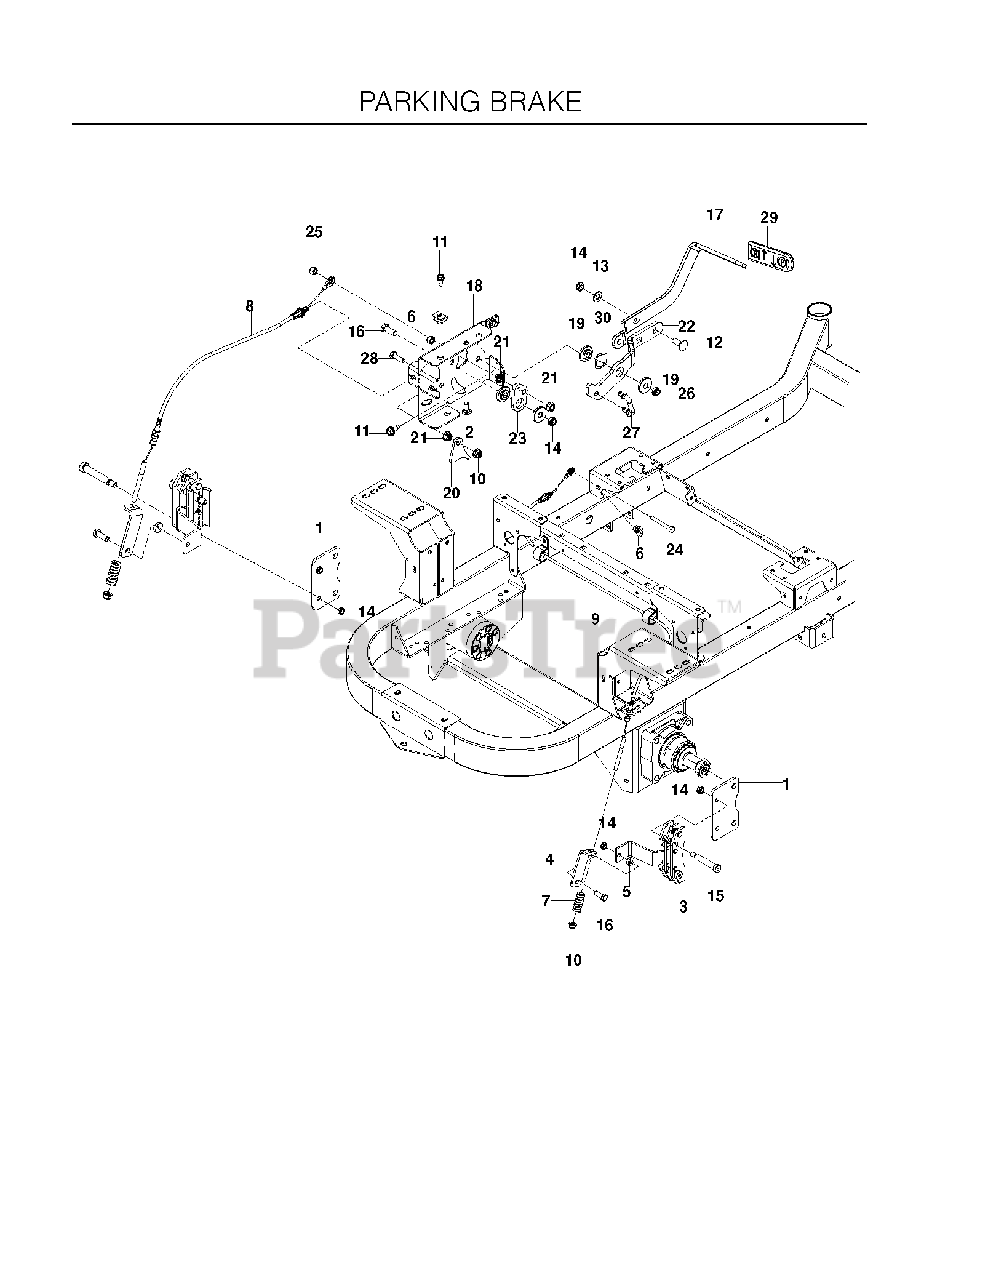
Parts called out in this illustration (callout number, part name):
1	PLATE, BRAKE
2	BOLT 5/16C X 3/4" CARRIAGE
3	CALIPER
4	BRACKET, L
5	WASHER 3/8 X 3/4 X .187 TK
6	U-CLIP 5/16-18 NUT RETAINER
8	CABLE, BRAKE, SHORT
9	CABLE, BRAKE, LONG
10	5/16-18 NYLOC FLANGE NUT
11	BOLT 5/16-18 X 3/4
12	RHSNB 3/8C X 1
13	WASHER 3/8 SAE FLAT
14	NUT HEX 3/8-16 NYLON, THIN
15	SB 3/8-16 X 2-1-1/2 SKT HDD ZD
16	HCS 3/8C X 1
17	ARM, BRAKE, BLK
18	MOUNT, BRAKE WLDMT
19	BUSHING, BRAKE
20	ACTUATOR, SWITCH
21	NUT 5/16C WHIZ
22	LEVER, BRAKE
23	BELLCRANK, BRAKE
24	HCS 5/16-18 X 2 1/2 TPBLT
25	NUT 5/16 NYLOC
26	NUT HEX 3/8-16 NYLON, THIN
27	LINKAGE, BRAKE
28	HCS 5/16C X 1
29	GRIP BRAKE HANDLE
30	WASHER, .825 X 1.087, WAVE
